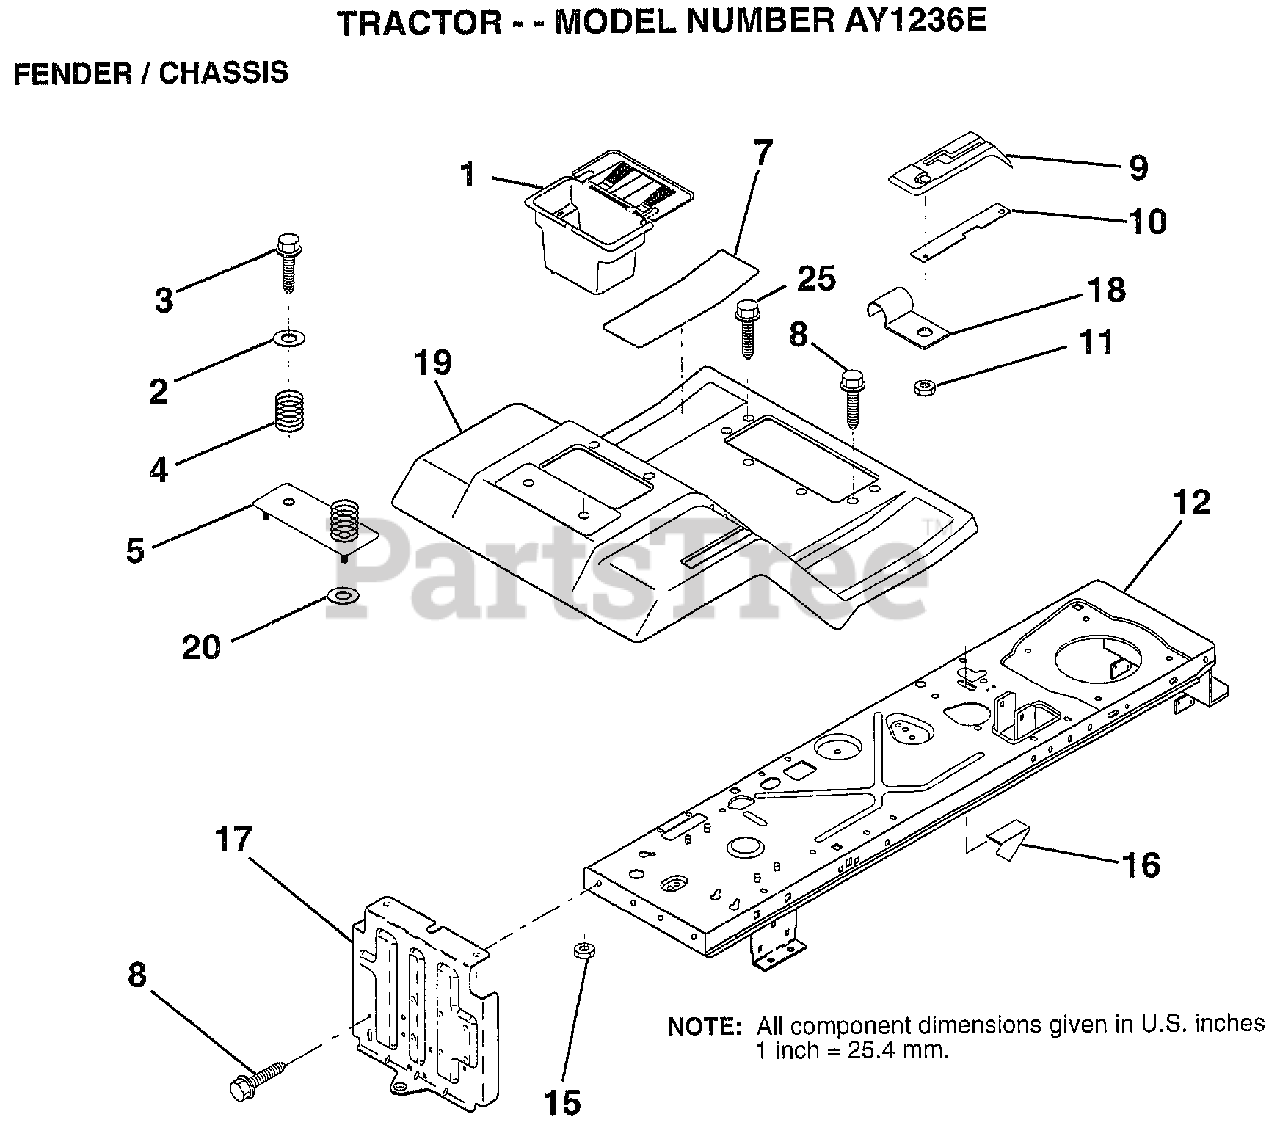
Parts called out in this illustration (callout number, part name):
1	"CASE,BATTERY.MECH"
2	WASHER
3	SCREW
4	SPRING COMPRESSIO
5	PLATE.FEND.LR.ASM
7	PAD FOOTREST
8	SCREW
9	CONSOLE.SHIFT CONTROL
10	PLATE LOCK SHIFT
11	NUT
12	CHASSIS, ASSY, WELDMENT
15	NUT HXKEP 1/4X20
17	DRAWBAR ASM LR
18	"CLIP,INSULATOR"
19	FENDER/FOOTREST
25	SCREW
